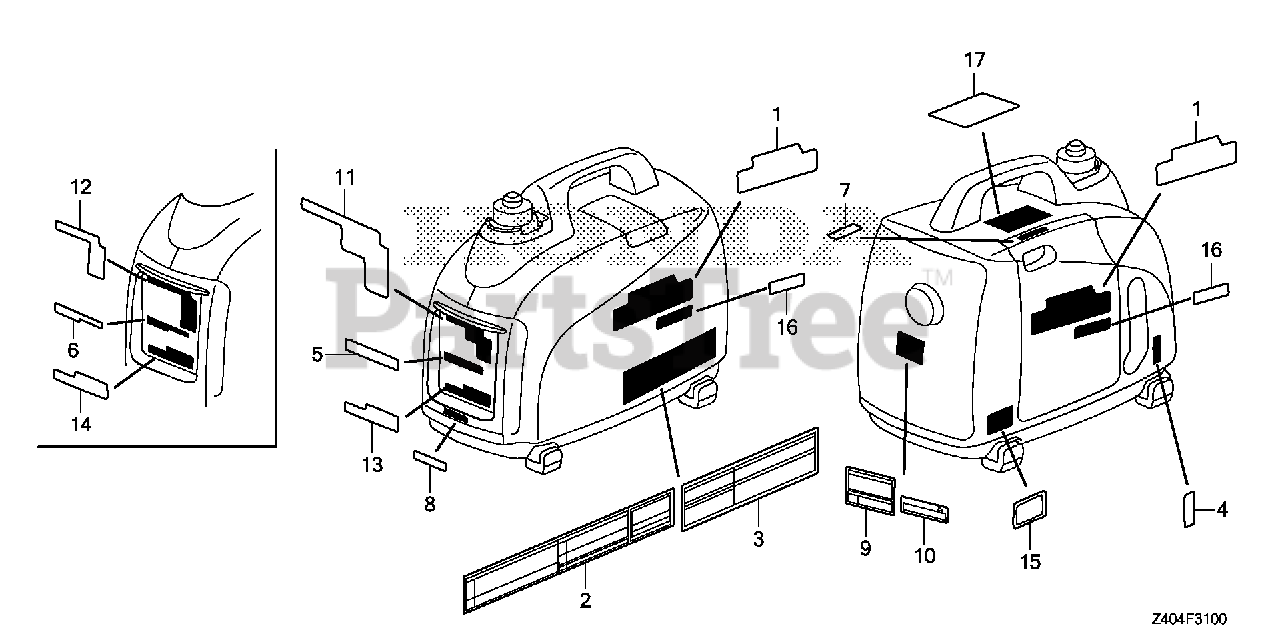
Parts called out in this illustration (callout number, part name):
1	EMBLEM (EU1000i)
2	MARK, CAUTION
4	MARK, ENGINE SWITCH
5	MARK, D.C. CAUTION
7	MARK, CHOKE
8	MARK, HONDA
9	MARK, EX. WARNING (E)
11	MARK, A.C. CAUTION
13	MARK, CIRCUIT PROTECTOR
15	MARK, OIL CAUTION
17	MARK, CPSC (CO CAUTION)
